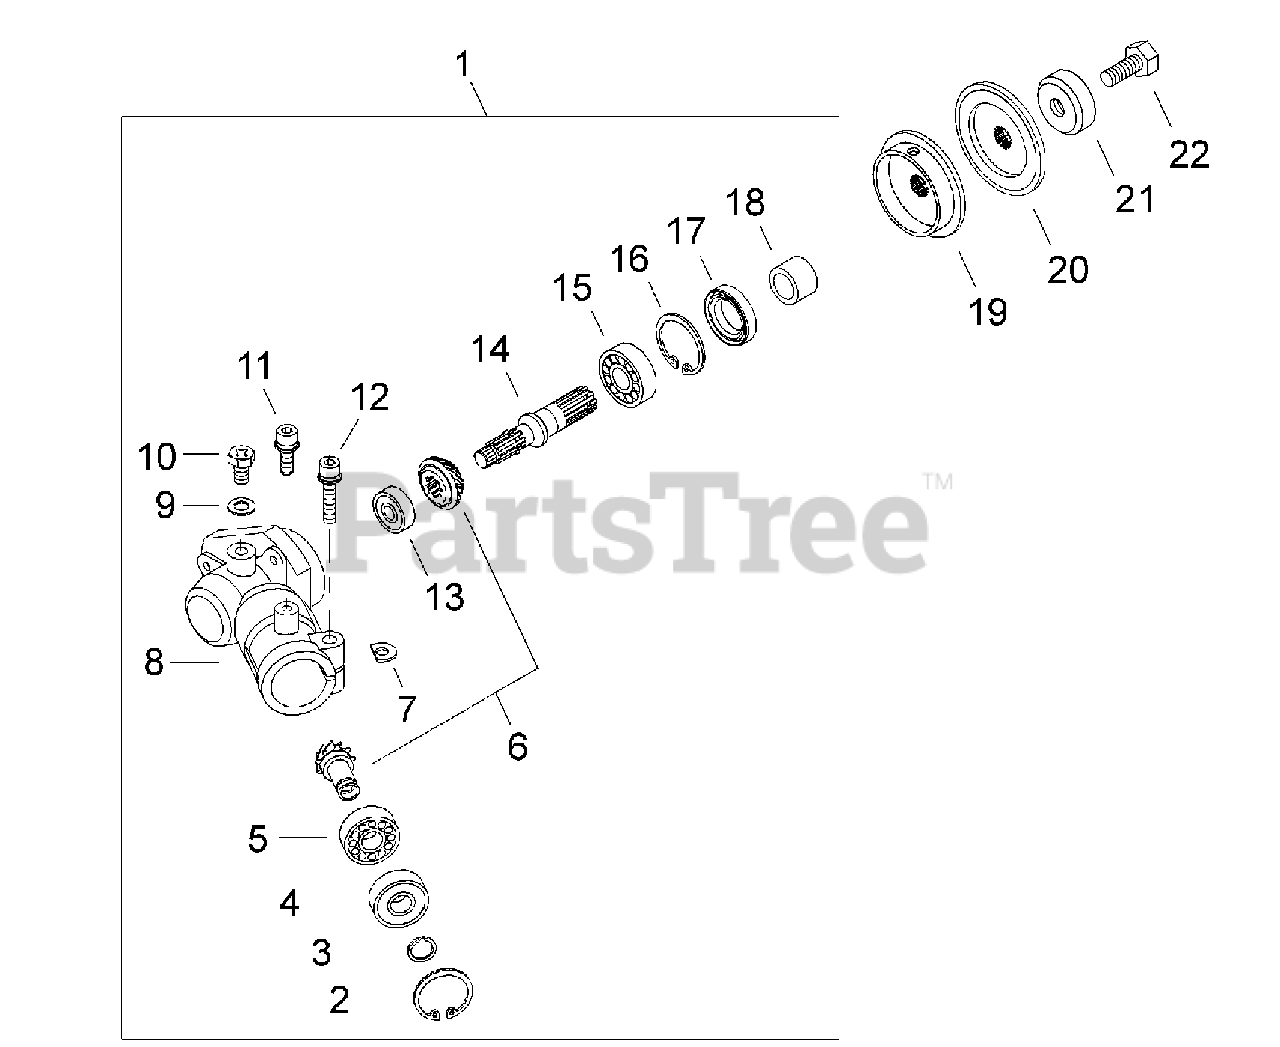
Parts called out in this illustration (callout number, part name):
1	GEAR CASE ASSY
2	RING, RETAINING - 24
3	RING, RETAINING
4	BEARING, BALL - 609ZZ
5	BEARING, BALL - 609
6	GEAR SET
7	SHIM
8	CASE, GEAR
9	WASHER - 6
10	BOLT - 6X10
11	SCREW - 5X16
12	SCREW - 5X25
13	BEARING, BALL - 608DDU
14	GEAR - SHAFT
15	BEARING, BALL - 6001
16	RING, RETAINING - 28
17	SEAL, OIL
18	COLLAR
19	HOLDER - A
20	ADAPTOR, BLADE - LOWER
21	GUARD
22	BOLT - 8 -- LEFT HAND
